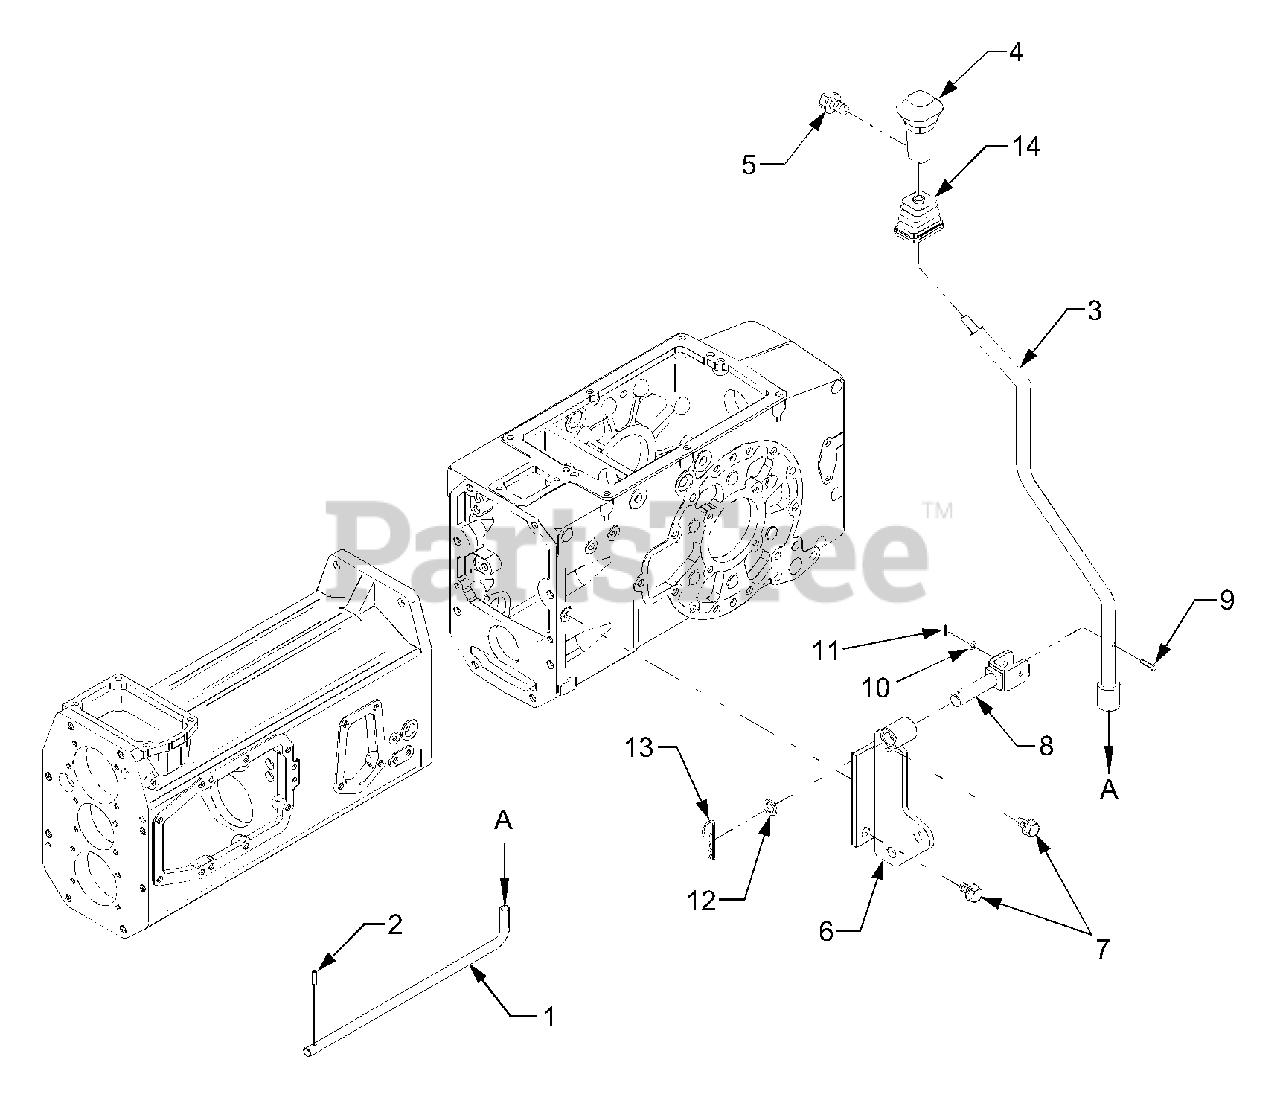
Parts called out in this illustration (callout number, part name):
1	Rod 1, Main Shift
3	Lever, Main Shift
4	Grip
6	Bracket, Main Shift
8	Pin, Main Shift
12	Washer, Plain
